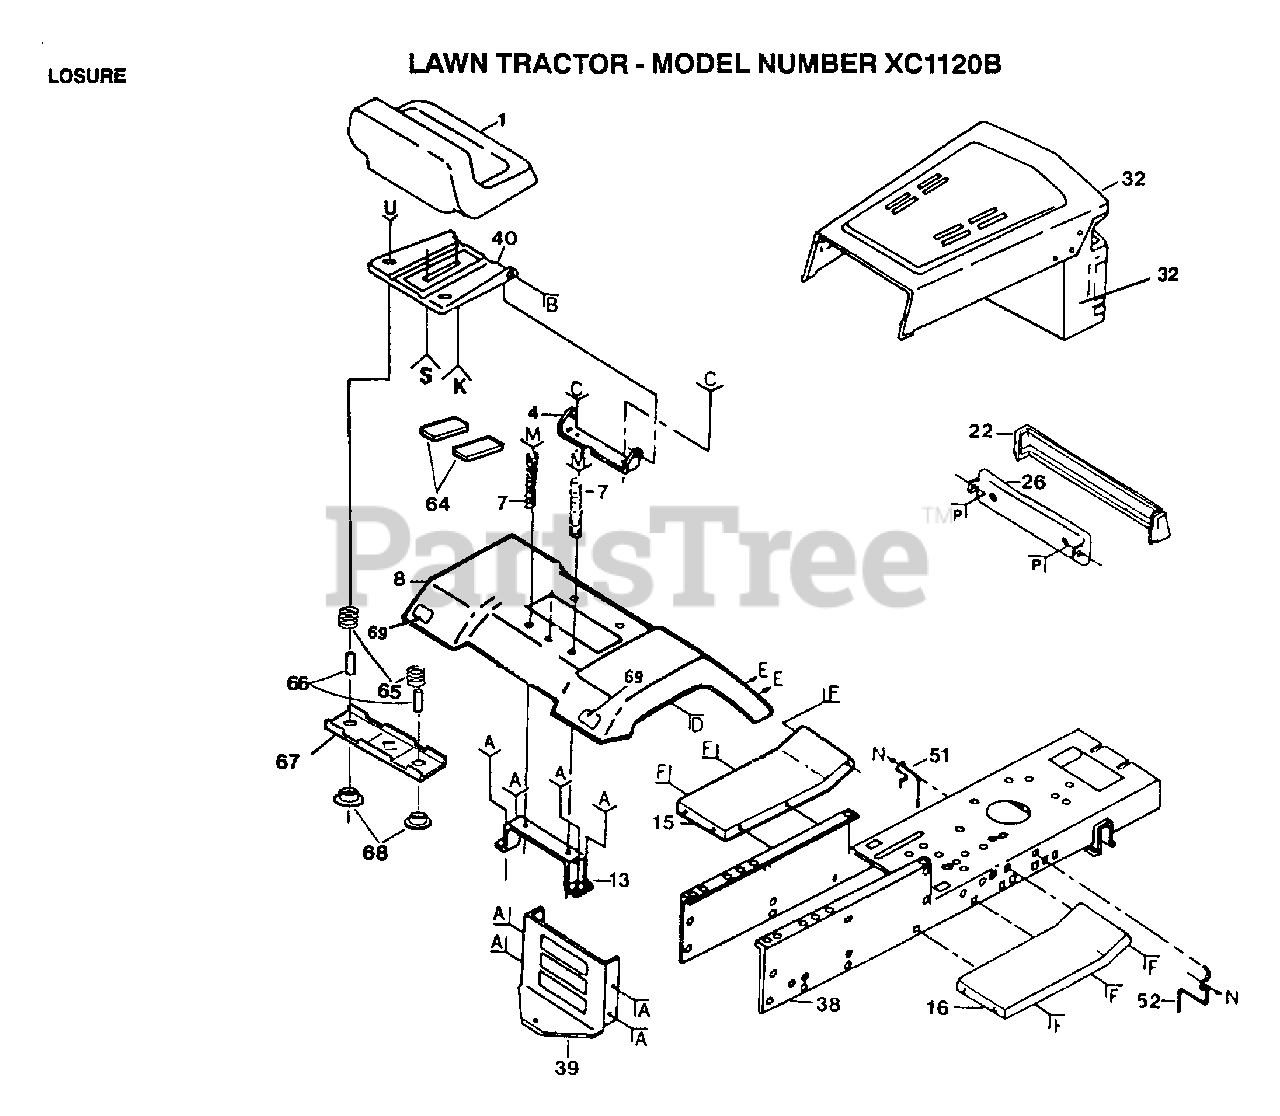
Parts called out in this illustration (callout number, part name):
7	SPRING COMPRESSIO
32	HOOD&GRILL ASSY
38	CHASSIS ASS'Y
51	BELT GUIDE
52	BELT GUIDE
65	SPRING
66	SPACER SPLIT
67	BRKT SWITCH
68	BUSHING
69	REFLECTOR-TAIL YT
